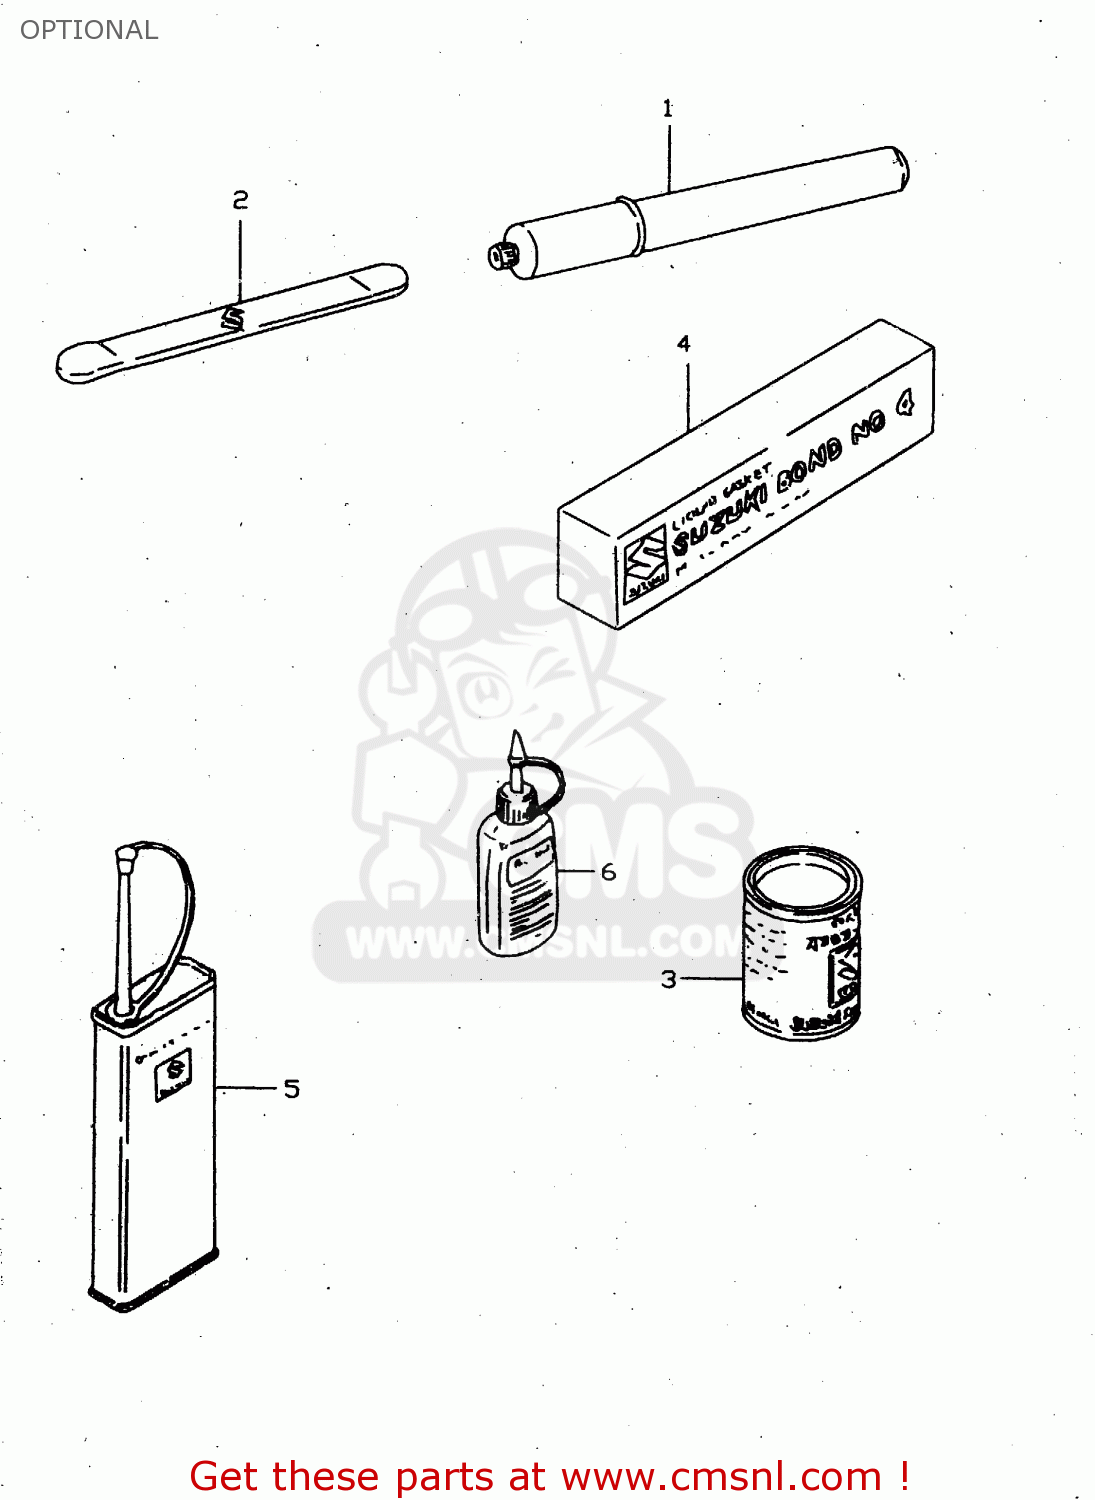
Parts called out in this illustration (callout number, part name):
1	INFLATOR, AIR
2	LEVER,TIRE
3	GREASE(C)EP2 LITHIUM 150G
4	BOND 1104
5	THREAD LOCK NO.1401 CLEAR 200G
6	** SUPERSEEDED
